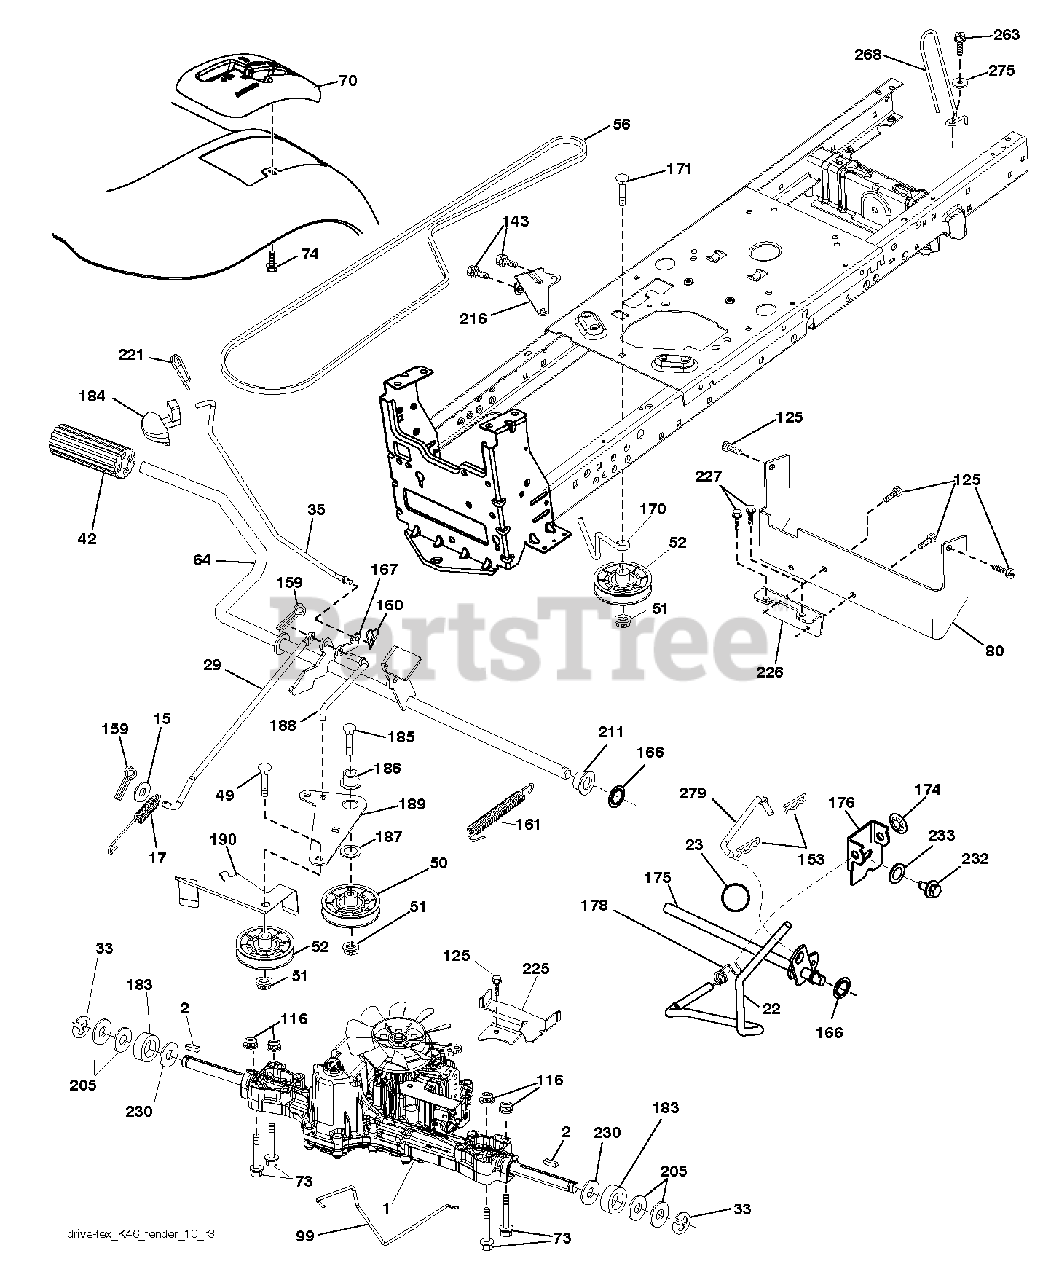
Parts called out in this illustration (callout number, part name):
2	SQUARE KEY
17	SPRING.BRAKE.K46.GREEN
22	ROD.SHIFT.FENDER.TLT.2006
23	PISTOL KNOB
29	ROD.BRAKE.K46
33	E-RING LT
35	ROD.BRAKE.PARTK.HUSQ.TEX
42	PEDAL COVER T
49	BOLT
50	IDLER.FLAT.910.OFFSET
51	NUT LOCK FLG 3/8-16 UNC
52	IDLER.V-GROOVE.910.OFFSET
64	SHAFT.ASM.PEDAL.BRAKE.
70	CONSOLE.SHIFT.STL.HYD.BLACK
74	SCREW.HI-LO.CONSOLE
80	STRAP.TORQUE.K46.K57R.TT
99	ROD.SPRING.BYPASS.K46.LT.Z
116	NUT LOCK HEX FLANGE 5/16-18
125	SCREW
153	RETAINER M
159	COTTER PIN
160	RETAINER CLIP
161	SPRING, RETURN LT
166	NUT.PUSH.625
167	LATCH.BRAKE.SPRING
170	KEEPER.V-IDLER.CENTER.
171	BOLT
174	NUT.PUSH.500.2006
175	SHAFT ASM SHIFT
176	ARM.CLEVIS.ROD.SHIFT
178	SPRING.SHIFT.GT2006
183	SPACER AXLE
184	HANDLE.PARKG.BRK.HUSQ/PRED.667
186	SPACER.RETAINER
187	WASHER 12/32X2X10GA
188	LINK.CLUTCH.GROUND.DRIVE
189	BELLCRANK.GROUND.DRIVE.TEX.
190	KEEPER.BELLCRANK.DRIVE
211	BUSHING.SHAFT.BRAKE.HAND
216	BRACKET.PULLEY.IDLER.W/TEX
221	RETAINER.SPRING.CLIP.H
225	KEEPER.BELT.TRANSAXLE.K46
226	BRACKET.MOUNT.TORQUE.K46.TLT
227	SCREW
230	WASHER.HARDENED
232	BOLT FIN HEX 7/16-14 X 1
233	WASHER SERRATED
263	SCREW, 3/8-16X3/4
275	WASHER
279	LINK SHIFT
